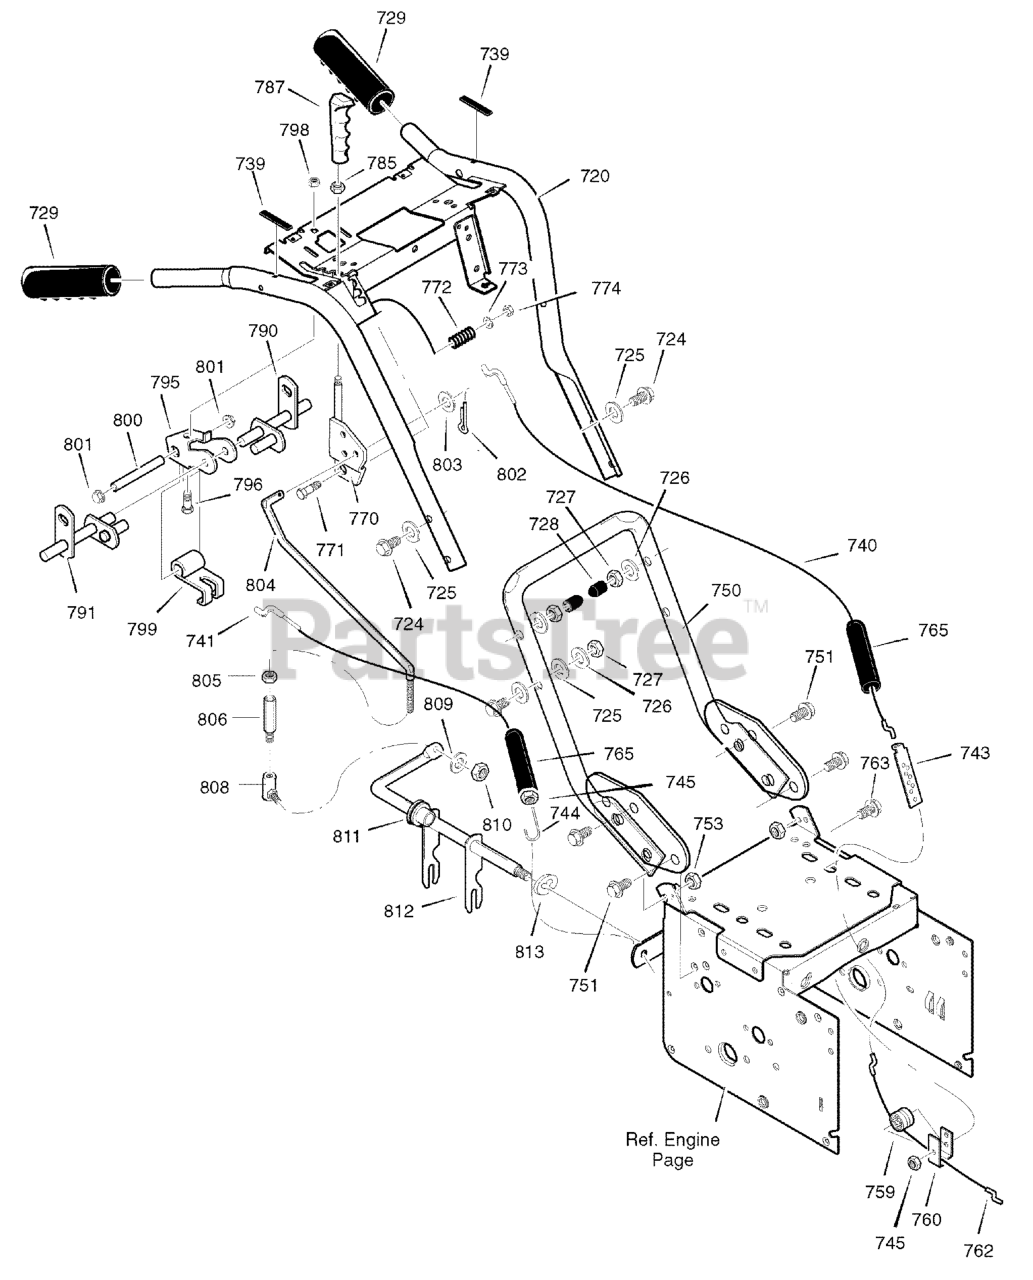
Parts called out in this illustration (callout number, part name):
720	ASSY, HANDLE
725	WASHER, FLAT
728	STOP, PLASTIC
729	GRIP, HANDLE
739	BUMPER
740	CABLE, AUGER CLUTCH
741	CABLE, DRIVE
743	BRKT, CABLE ADJ
744	SPRING, CLUTCH
745	NUT, HEX
750	HANDLE, LOWER
753	NUT, 5/16-18
759	SPOOL, CABLE
760	BRKT, SPOOL
762	CABLE, LOWER DRIVE
763	BOLT, HEX 1/4-20 x 1.5
765	BOOT, CABLE
770	BRACKET, SHIFT
773	WASHER, FLAT
774	NUT, HEX
785	NUT, HEX
787	KNOB, SHIFT
790	ROD, ASSY LH
791	ROD, ASSY RH
795	BRACKET, CAM
798	NUT, NYLOCK
799	CAM LOCK
800	PIN, SPRING PIVOT
801	NUT, PUSH ON
802	PIN, COTTER
803	FLATWASHER
804	ROD, SPEED CONTROL
805	NUT, 5/16-18
806	ADAPTER, ROD
808	BALLJOINT, STEEL
810	NUT, 5/16-18
811	BEARING, FL
813	RETAINER, RING
